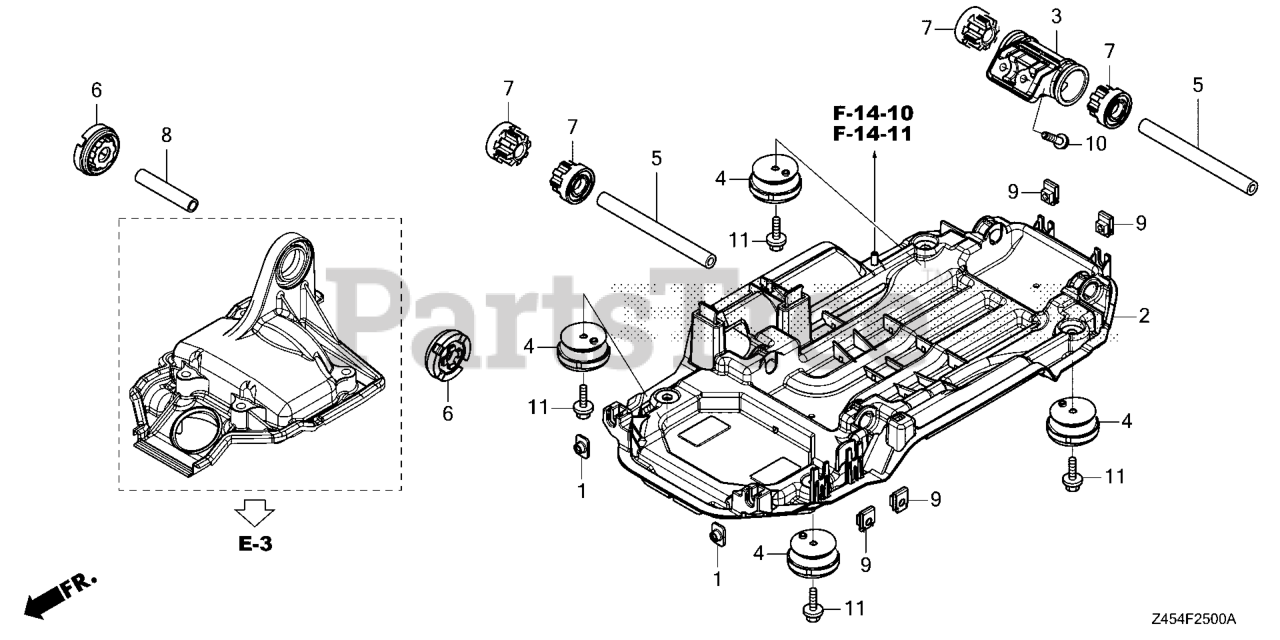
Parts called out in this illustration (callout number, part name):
1	NUT, SPECIAL (6MM)
2	FRAME, BASE
3	BRACKET, ENG MOUNT
4	MOUNT (LOWER)
5	COLLAR A, INSULATOR
6	ENG MOUNT (UPPER)
7	ENG MOUNT (LOWER)
8	COLLAR B, INSULATOR
9	NUT, FENDER SETTING
10	BOLT, FLANGE (6X25) Use up to Engine SN 2056819.
11	BOLT, FLANGE (6X10)
